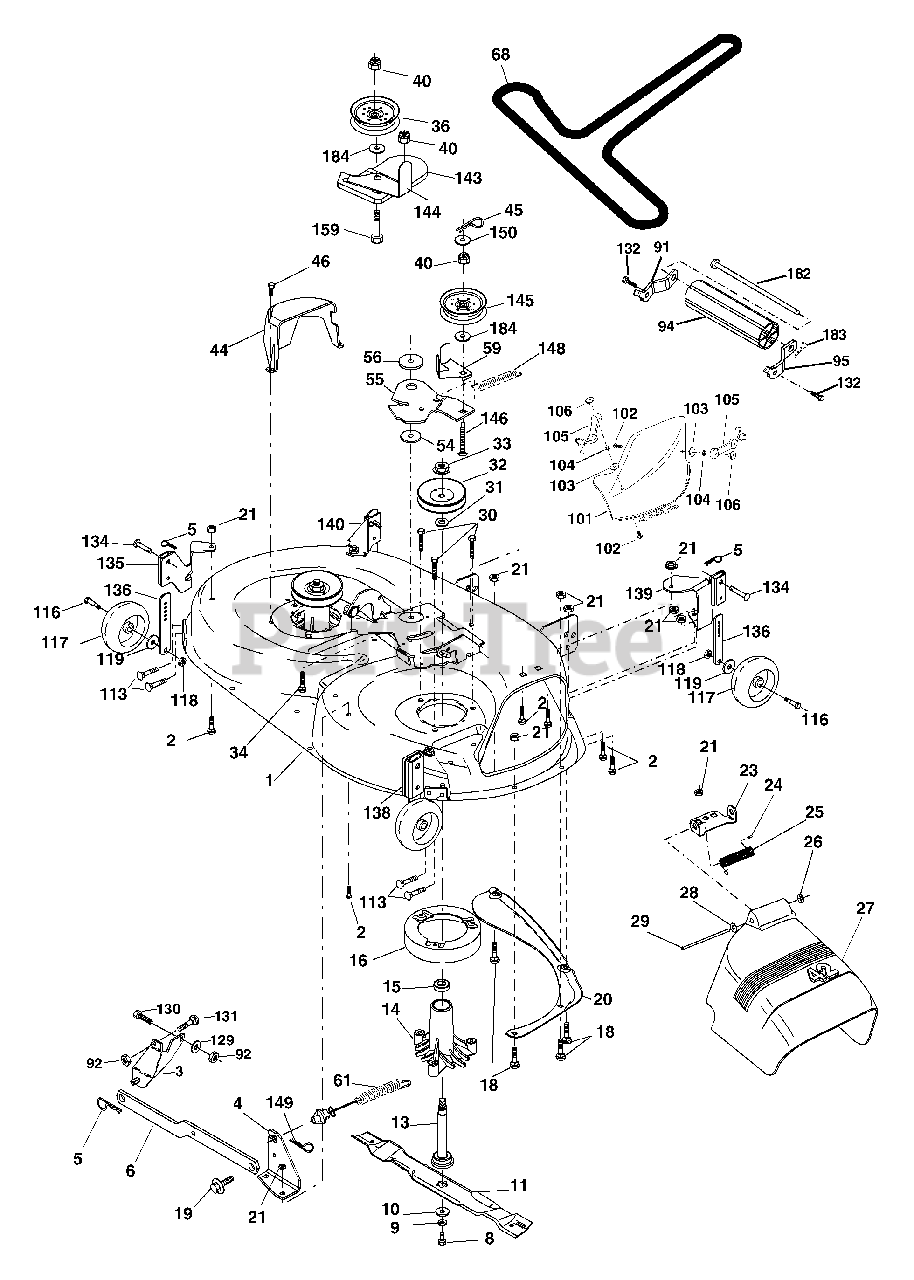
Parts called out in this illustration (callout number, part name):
1	Mower Housing
2	Bolt
3	Bracket Assembly, Sway Bar, Front
4	Bracket Sway Bar 38/42"
5	Retainer Spring
6	Bar Sway Deck
8	Bolt, Hex 3/8-24 x 1.25 Gr. 8
9	Washer, Lock
10	Washer, Hardened
11	Blade, 42" Mulching STD
11	Blade, 42" Mulching Premium
11	Blade, 42" Hi-Lift
13	Shaft Assembly, Mandrel, Vented
14	Housing, Mandrel, Vented
15	Bearing, Ball, Mandrel
16	Stripper, Mower Deck
18	Bolt, Carriage 5/16-18 x 5/8
19	Bolt, Shoulder
20	Baffle, Vortex
21	Nut, Crownlock 5/16-18 unc
23	Bracket, Deflector
24	Cap, Sleeve
25	Spring, Torsion, Deflector
26	Nut, Push
27	Shield, Deflector
28	Washer 11/32 x 5/8 x 16 Ga.
29	Rod, Hinge
30	Screw Thdrol Rolling Wsh Hd
31	Washer, Spacer
32	Pulley, Mandrel
33	Nut, Toplock, Flanged
34	Bolt
36	Pulley, Idler, Flat
37	Washer 13/32 x 13/16 x 16 Ga.
40	Nut, Lock 3/8-16 unc
44	Guard, Mandrel, L.H.
45	Retainer
46	Screw, Thd. Roll 1/4-20 x 5/8
54	Washer, Hardened
55	Arm, Idler
56	Spacer, Retainer
59	Guard, Tuv Idler
61	Spring Ext Elect Clutch
68	V-Belt
91	Bracket Roller Nose LH
92	Locknut, Hex W/Wsh 3/8-16 unc
94	Roller Nose
95	Bracket Roller Nose RH
101	Cover Mulching 42" Black
102	Screw Truss Hd Phil10-24 x 5/8
103	Washer #10
104	Washer Lock
105	Latch Asm Bagger
106	Nut Weld
113	Screw 5/16-18
116	Bolt, Shoulder
117	Wheel, Gauge
118	Nut, Crownlock 3/8-1
119	Washer 13/32 x 7/8 x 14 Ga.
129	Washer 13/32 x 13/16 x 12 Ga.
130	Bolt, Fin Hex 3/8-16 unc x 1Gr. 5
131	Bolt Rdhd Sqnk 3/8-16 unc x 1
132	Screw 3/8-16 x 3/4
134	Pin Head Rivet
135	Bracket Asm. Wheel Gauge Rear LH
136	Bar Adj. Gauge Wheel
138	Bracket Asm. Wheel Gauge Rear RH
139	Bracket Asm. Wheel Gauge Front RH
140	Bracket Asm. Wheel Gauge Front LH
143	Bracket Arm Idler 42"
144	Keeper Belt 42" Clutch Cable
145	Pulley Idler Flat
146	Bolt Carriage Idler
148	Spring Return Idler
149	Retainer Spring Yellow Zinc
150	Washer 9/32 x 3/4 x 10 Ga.
159	Bolt Rdhd Sqn 3/8-16 unc x 1-3/4
182	Rod Roller Nose
183	Retainer Spring
184	Washer 3/8
